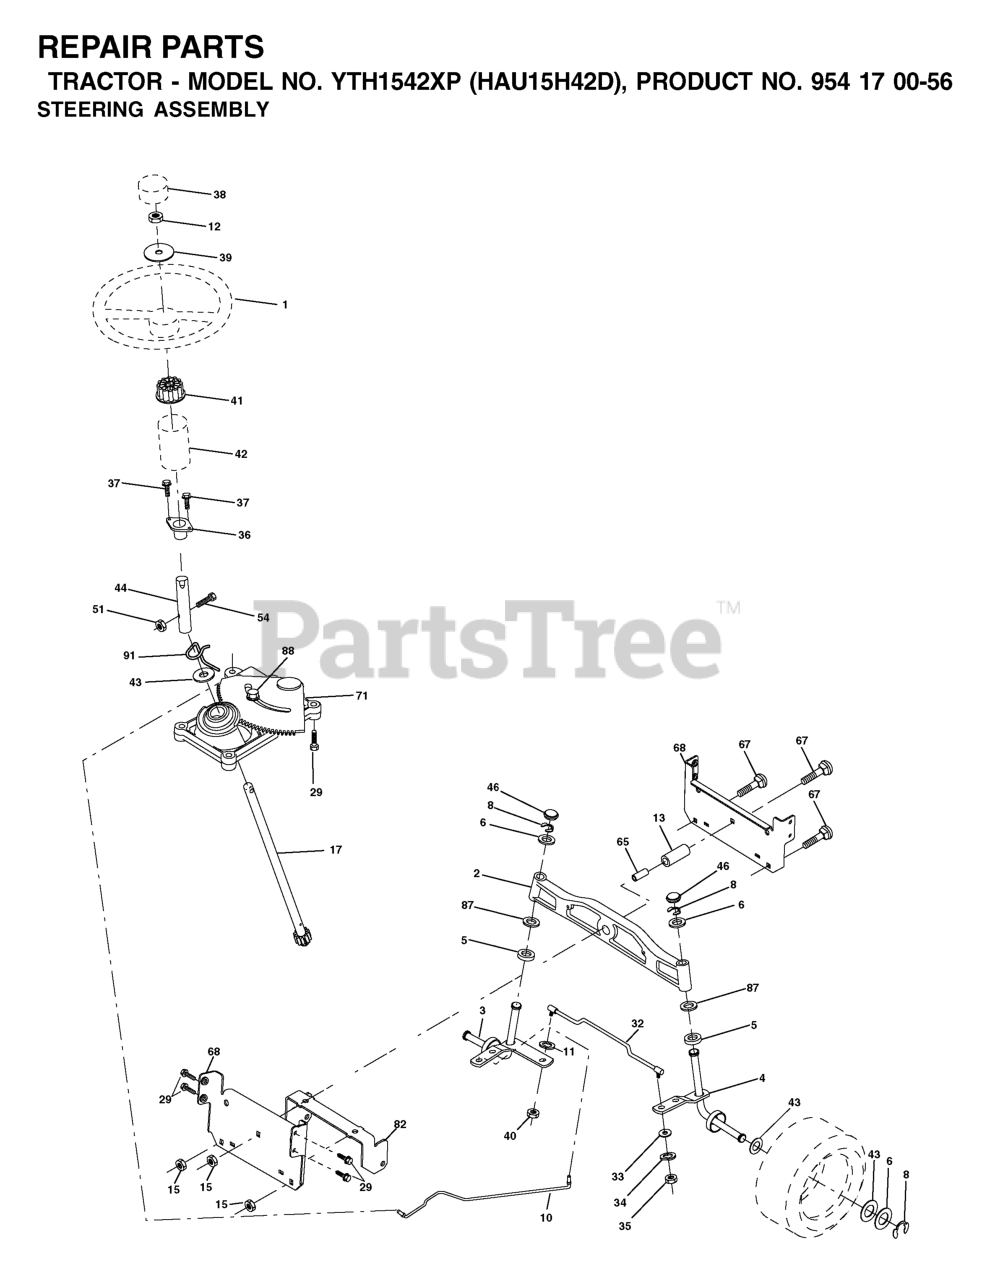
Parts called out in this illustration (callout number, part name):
1	STEERING WHEEL
2	AXLE ASM
3	SPINDLE.ASM.LH.15"TIRES
4	SPINDLE.ASM.RH.15"TIRES
5	THRUST WASHER
10	DRAGLINK.15".TIRES.2001
11	WASHER, LOCK 3/8
12	NUT.HEX.1/2-20
13	TUBE, PIVOT AXLE
15	NUT
17	SHAFT ASM, STEERING
29	SCREW 3/8-16X3/4
32	TIE ROD
33	WASHER M
34	WASHER.LOCK.HVY.HLCL.SPR.5/16
35	NUT, CROWNLOCK
36	BUSHING, STEERING
37	SCREW.TT.#10-32X.5.3/8.FLANGE
38	CAP.WHEEL.STEERING.GREY
39	Washer 9/16 ID x 1 1/2 OD 11 Ga. Zin
40	GRIPCO NUT
41	STEERING WHEEL ADAPTOR
42	BOOT STEERING
44	EXT, STEERING SHAFT
46	CAP.SPINDLE.BLACK
51	NUT.CROWNLOCK.1/4-28
54	Bolt Hex 1/4-28 unf x 1-1/4 Gr. 8
63	BOLT
65	SPACER BRACE AXLE
67	BOLT
68	BRACE.AXLE.15"TIRES
71	STEERING ASM
82	BRACKET
87	WASHER, FLAT .781 X 1 1/2"
88	BOLT, SHOULDER 7/16-20
91	CLIP.STEERING
